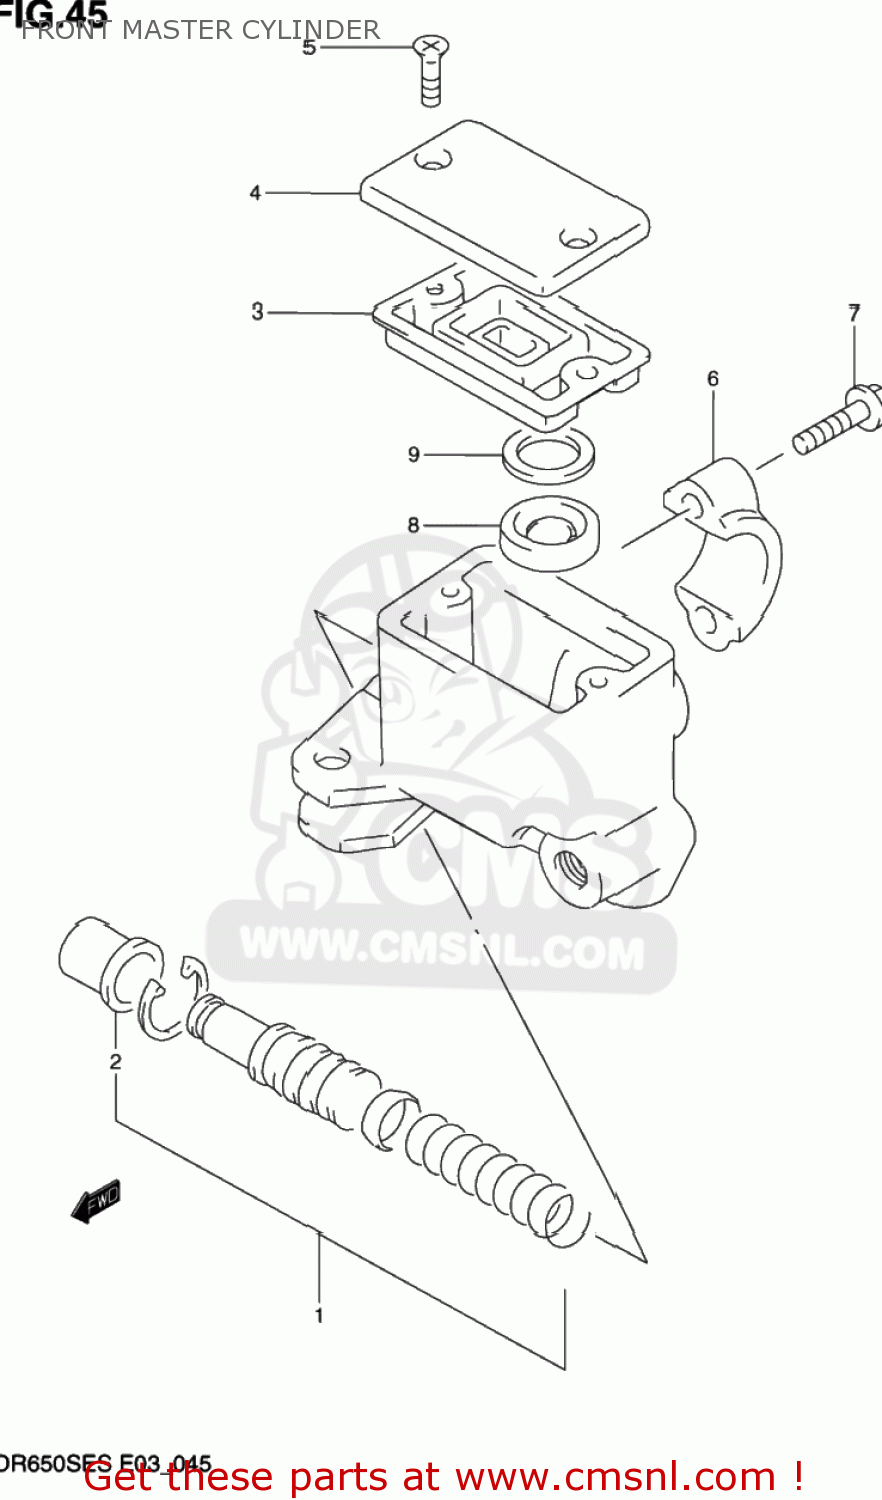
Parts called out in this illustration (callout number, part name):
1	PISTON & CUP SET
2	BOOT
3	DIAPHRAGM
4	CAP
5	SCREW
6	HOLDER
7	BOLT(6X25)
8	SEPERATOR
9	PLATE
